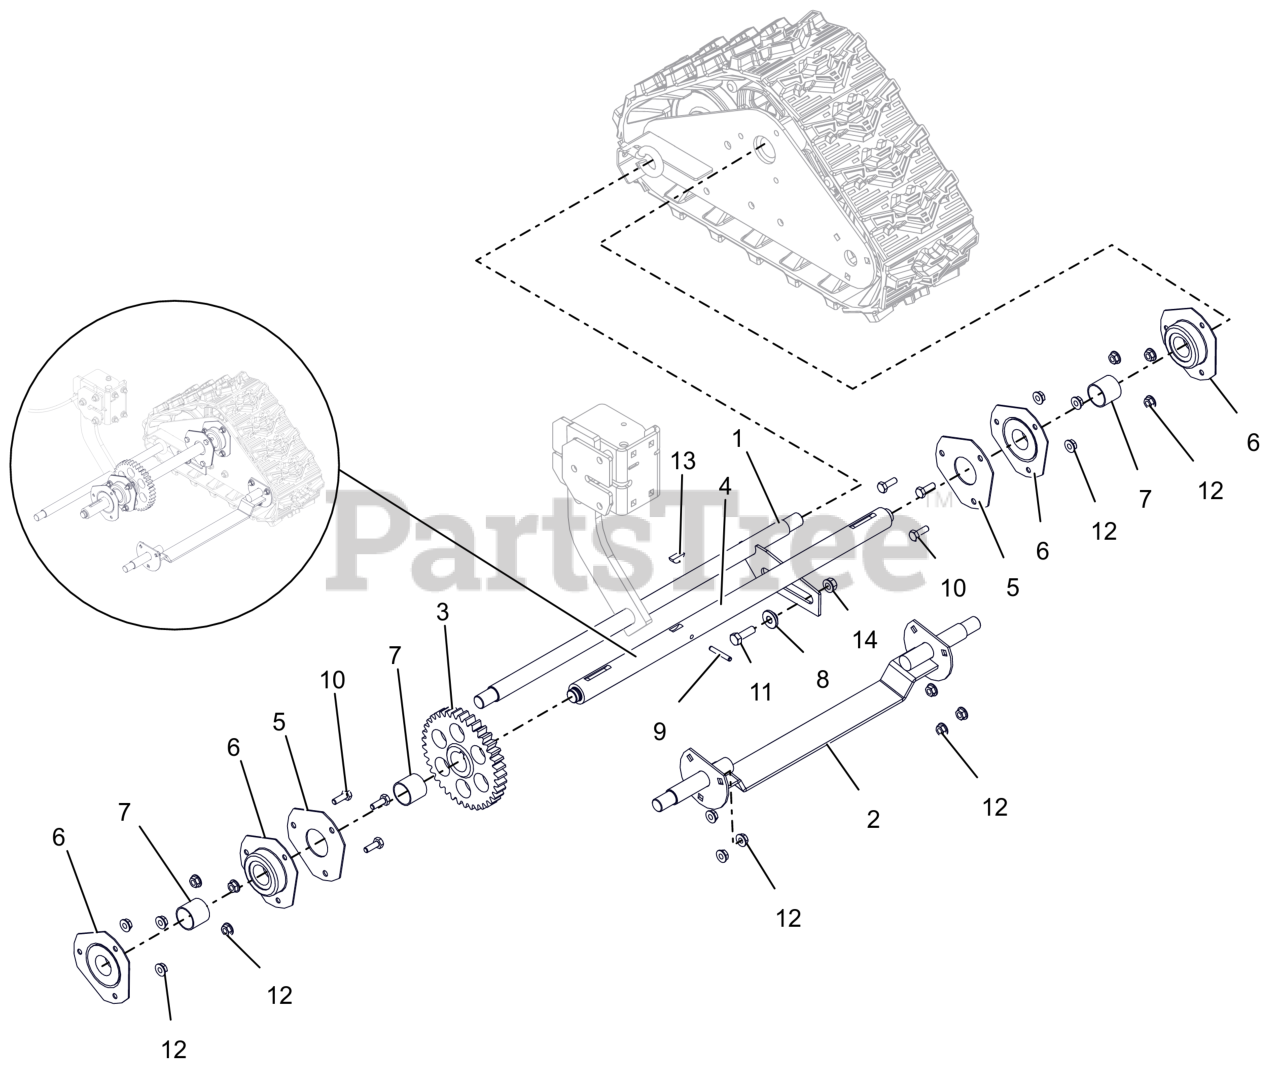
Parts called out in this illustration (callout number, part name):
1	AXLE, REAR - DELUXE TRACK
2	AXLE, FRONT-COMPACT TRACK
3	GEAR, SPUR
4	AXLE, TRACK-DELUXE
5	PLATE, BEARING SPACER
6	BRG-FLG 1.003/1.000 3 BOLT
7	BSHG-SLV, 1.012X1.125X1.00
8	BSHG-FLG .325X.499X.3X.875
9	PIN-ROLL .188X1.25
10	BLT, HEX .25-20X.75 G5 ZCC
11	BLT,HEX .31-18X1.00 G5 ZCC
12	NUT-LK-CTR-FLG .25-20 ZC120
13	KEY-WDRF .25X.750X.313 SAE91
14	NUT-LK-TOP-FLG .312-18 GF ZCC
